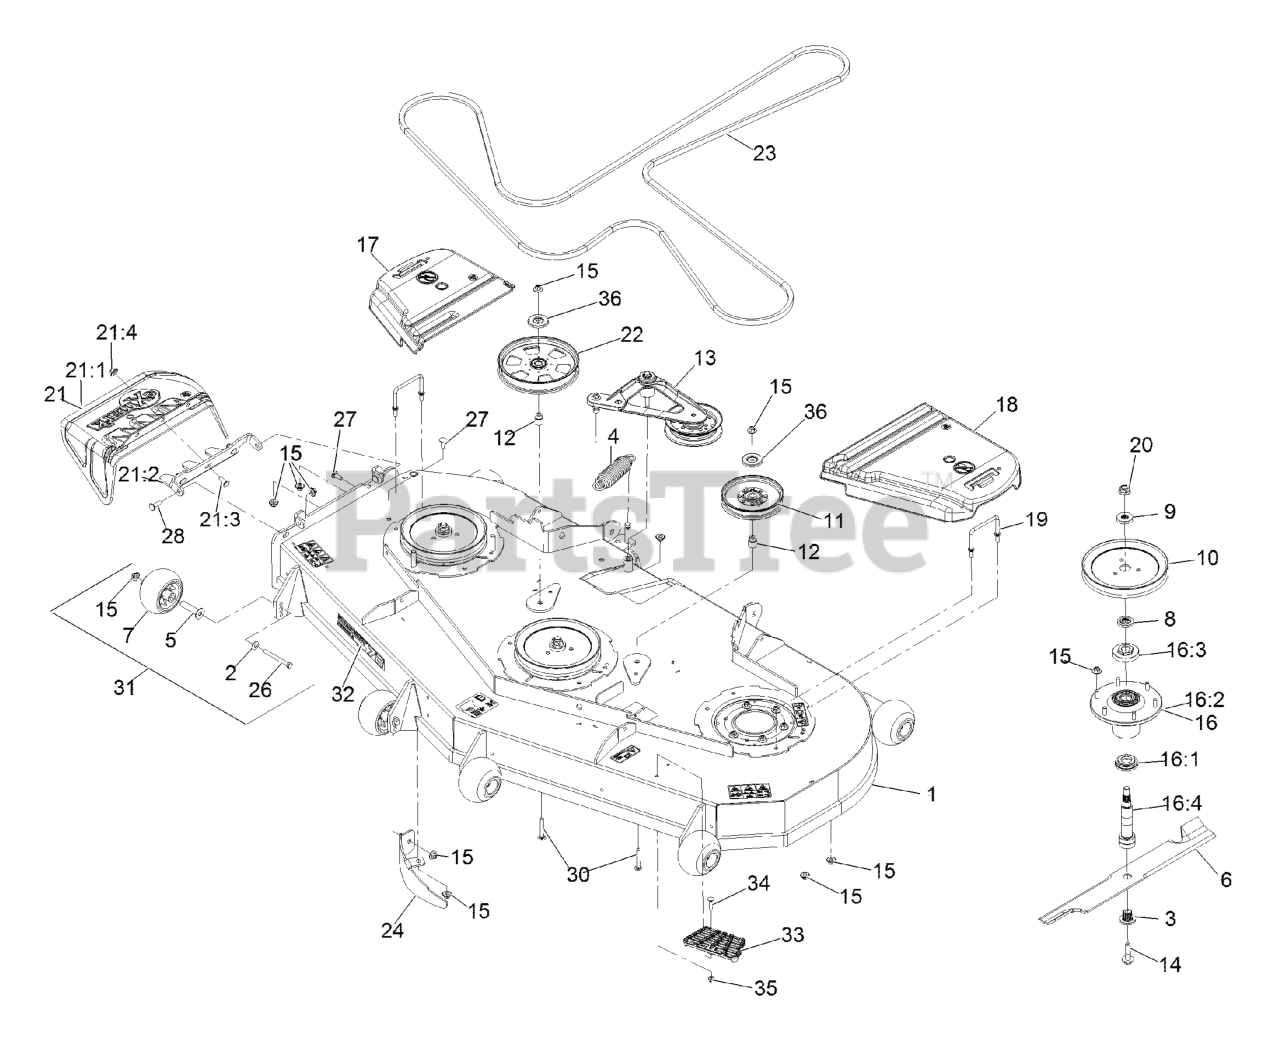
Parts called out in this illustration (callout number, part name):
1	ASM,DECK W/DECALS 724
2	WASHER-BELLEVILLE
3	BUSHING,SPLINED
4	SPRING-EXTENSION
5	AXLE, ROLLER
7	ROLLER-SCALP, ANTI
8	SPACER,SPLINED STEPPED
9	SPACER,SPLINED
10	SHEAVE,BLADE DRIVE 9.00
11	IDLER-PULLEY
12	BUSHING-IDLER
13	DECK IDLER ASM
14	SCREW,SEMS 1/2-20 X 2.19
15	Nut-Nyloc 3/8-16 Flg
16	ASM,SPINDLE HOUSING
16:1	GUARD,BOTTOM
16:2	ASM,CUTTER HOUSING
16:3	NUT, SPINDLE 7/8-14
16:4	SPINDLE,DOUBLE SPLINE
17	COVER-BELT, RH
18	COVER-BELT, LH
19	WIREFORM-COVER
20	NUT-FLANGE, CENTERLOCK
21	ASM,DISCHARGE CHUTE
21:1	CHUTE,DISCHARGE
21:2	BRACKET,DISCHARGE CHUTE
21:3	SCREW-CARR
21:4	Nut-Nyloc 3/8-16 Flg
22	PULLEY-IDLER, FLAT
23	BELT-V
24	BAFFLE-DOGLEG, LZ72
26	SCREW-HH 3/8-16 X 3 3/4 GR 8
27	SCREW-CARR
28	Bolt-Carriage 3/8-16 X 1 1/4
30	SCREW-CARR
31	KIT, ANTI-SCALP ROLLER
32	DECAL, 726
33	STEP-DECK
34	Bolt-Carriage 5/16-18 X 1 1/4
35	NUT-HF, NI
36	SHIELD-DUST
